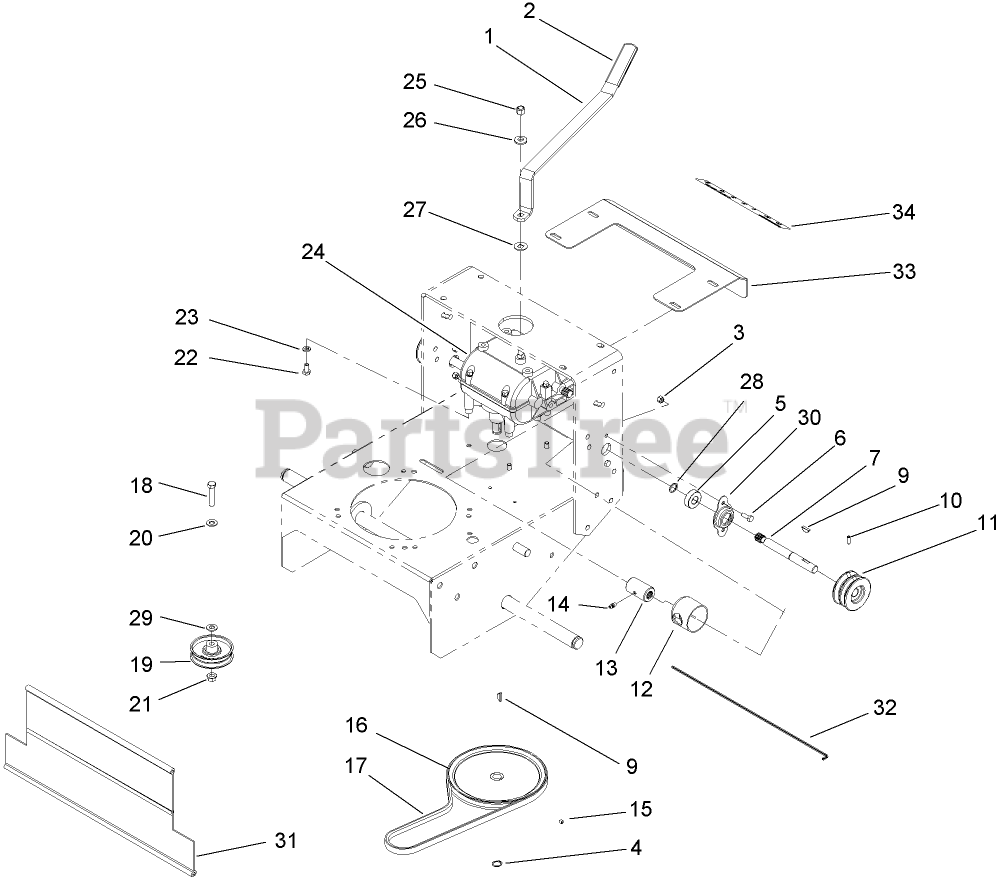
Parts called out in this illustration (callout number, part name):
1	LEVER-SHIFT
3	NUT-LOCK, NI
4	RING-SNAP, EXTERNAL
5	BEARING-SHAFT
6	SCREW-HH
7	SHAFT-OUTPUT
9	KEY-WOODRUFF
10	SCREW-SET, HS
11	PULLEY-TRANSMISSION
12	GUARD-COUPLER
13	COUPLER
14	FITTING-GREASE
15	SCREW-SET, HSH
16	PULLEY-DRIVEN
17	BELT V
18	SCREW-HH
19	PULLEY-IDLER
20	WASHER-FLAT
21	NUT-HF
22	SCREW-HH
23	WASHER-LOCK
24	TRANSMISSION
25	NUT-LOCK
26	WASHER-BELLEVILLE
27	WASHER
28	RING-RETAINING
29	WASHER-FLAT
30	FLANGE-OUTPUT
31	SHIELD-TRAILING
32	ROD-SHIELD
33	PLATE-GATE, SHIFT
34	DECAL-SPEED, GROUND
